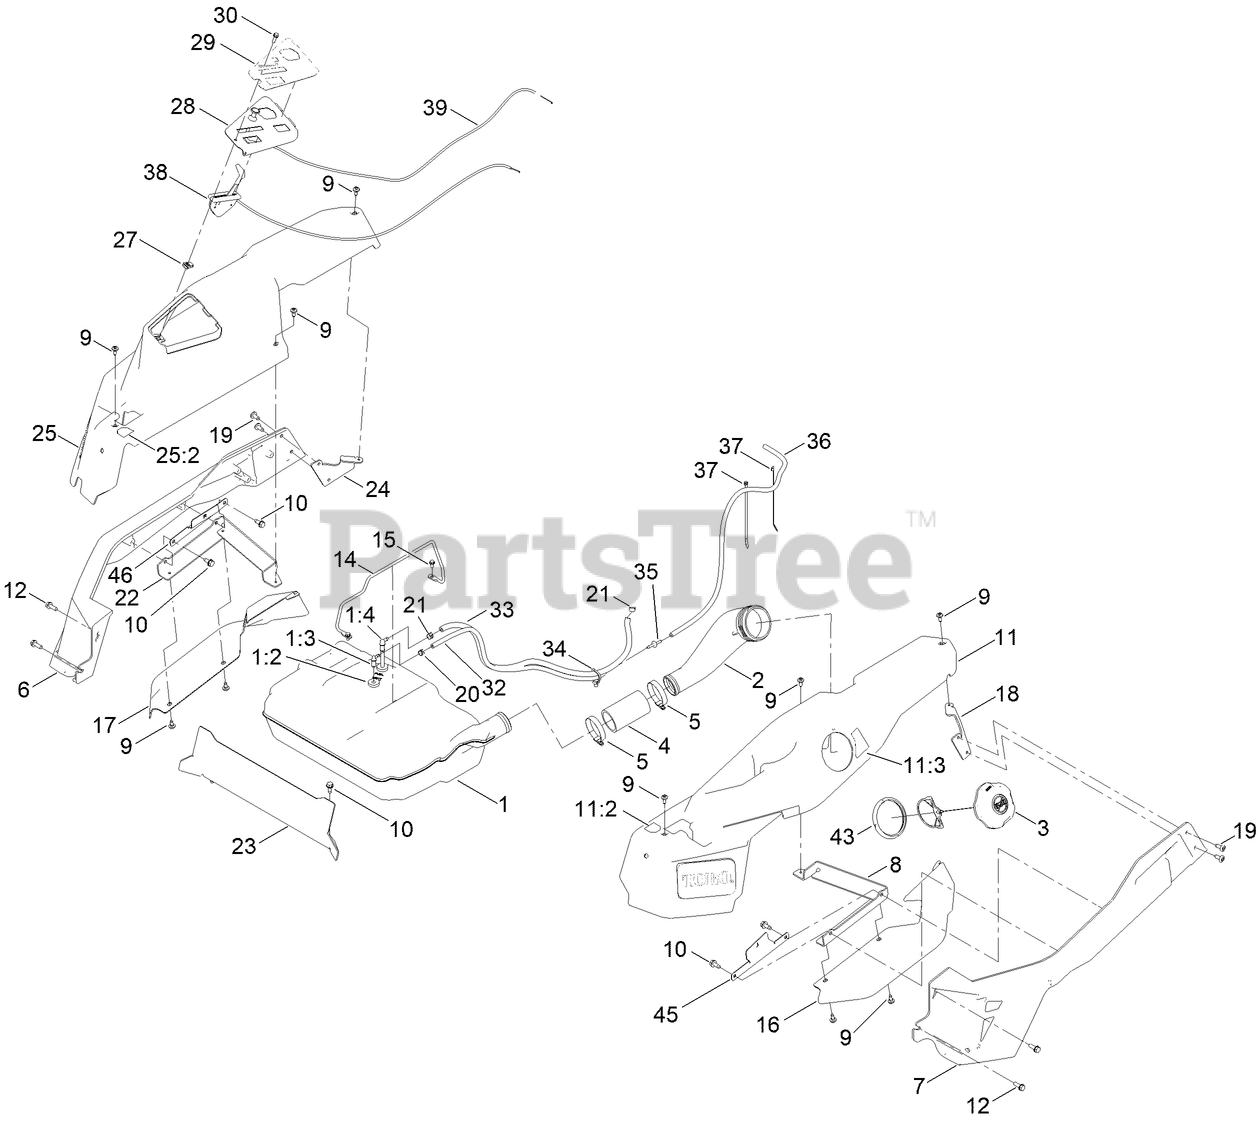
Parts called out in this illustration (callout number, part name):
1	TANK-FUEL ASM
1:2	BUSHING
1:3	FITTING-ELBOW 90
1:4	FITTING - PICKUP, FUEL
2	NECK-FILLER, FUEL
3	CAP-FUEL, RATCHETING
4	HOSE-FILLER, FUEL
5	CLAMP-HOSE
6	CAST-TUBE, RH [RED]
7	CAST-TUBE, LH [RED]
8	MOUNT-POD BRACKET LH
9	SCREW-SHOULDER
10	SCREW-HWHTF
11	POD ASM - LH W/DECALS
11:2	DECAL-CONTROL LEVER, LH
11:3	DECAL-FUEL FILL
12	SCREW-TAPTITE
14	ROD-HOLD DOWN
15	SCREW-HWH
16	FENDER-TIME CUTTER, LH
17	FENDER-TIME CUTTER, RH
18	BRACKET-REAR POD, LH
20	CLAMP-HOSE
21	CLAMP-HOSE
22	MOUNT-POD BRACKET RH
23	PLATE-KICK
24	MOUNT-POD BRACKET RH
25	POD ASM - RH W/DECALS
25:2	DECAL-CONTROL LEVER, RH
28	PANEL-CONTROL
29	DECAL - CONTROL PANEL W/OUT HOUR METER
30	SCREW-HWH
32	HOSE-FUEL
33	HOSE-FUEL
34	CLIP-TIE
35	ADAPTER ORIFICE
36	HOSE-LP
37	TIE-CABLE
38	CABLE-THROTTLE
39	CABLE-CHOKE
43	RING-RETAINING
45	BRACKET-ALIGNMENT, POD LH
46	BRACKET- ALIGNMENT, POD RH
